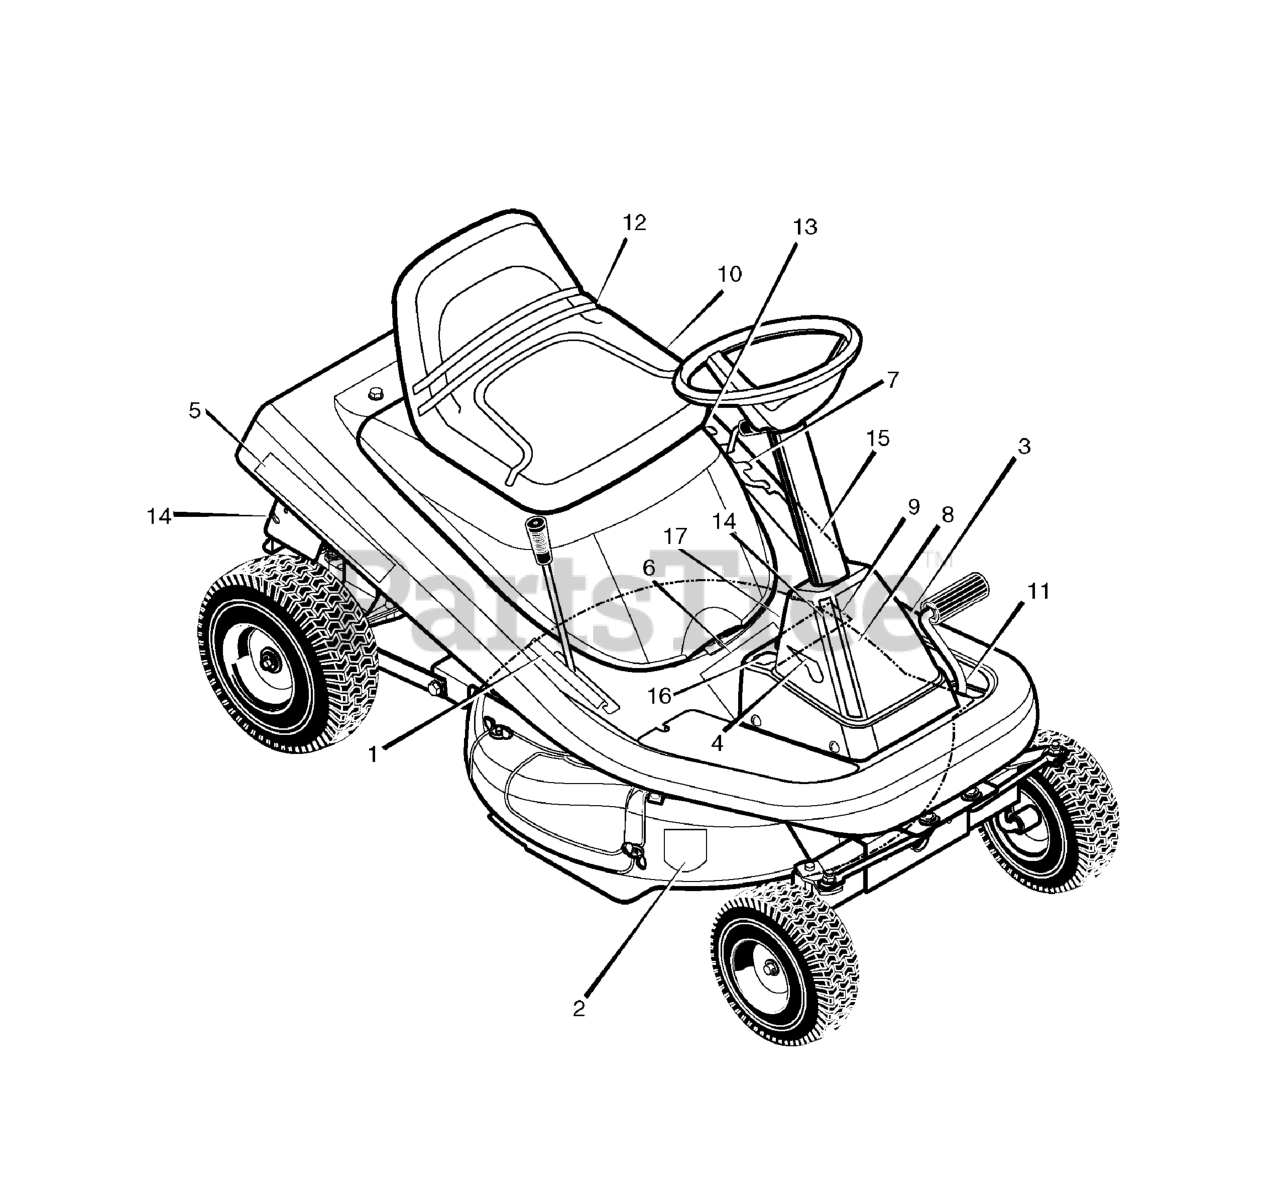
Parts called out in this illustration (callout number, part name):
1	DECAL, ENGAGEMENT
2	DECAL, ENGLISH CUT FINGER
3	DECAL, 13.5 Murray Auto LH
4	DECAL, 13.5 Murray Auto RH
5	DECAL, Murray White/Clear
6	DECAL, WARNING
7	DECAL, Height Adjust, 1-5
8	DECAL, CAUTION NO STEP
9	DECAL, PARKING BRAKE SYMBOL
10	DECAL, THROTTLE CONTROL
11	DECAL, CLUTCH BRAKE
12	DECAL, GAS GUAGE
13	DECAL, HEAT SHIELD WARNING
14	DECAL, DRAWBAR WARNING
15	DECAL, DECK LEVEL POSITION
16	DECAL, AUTO DISCONNECT
17	DECAL, STARTING INSTRUCTIONS
